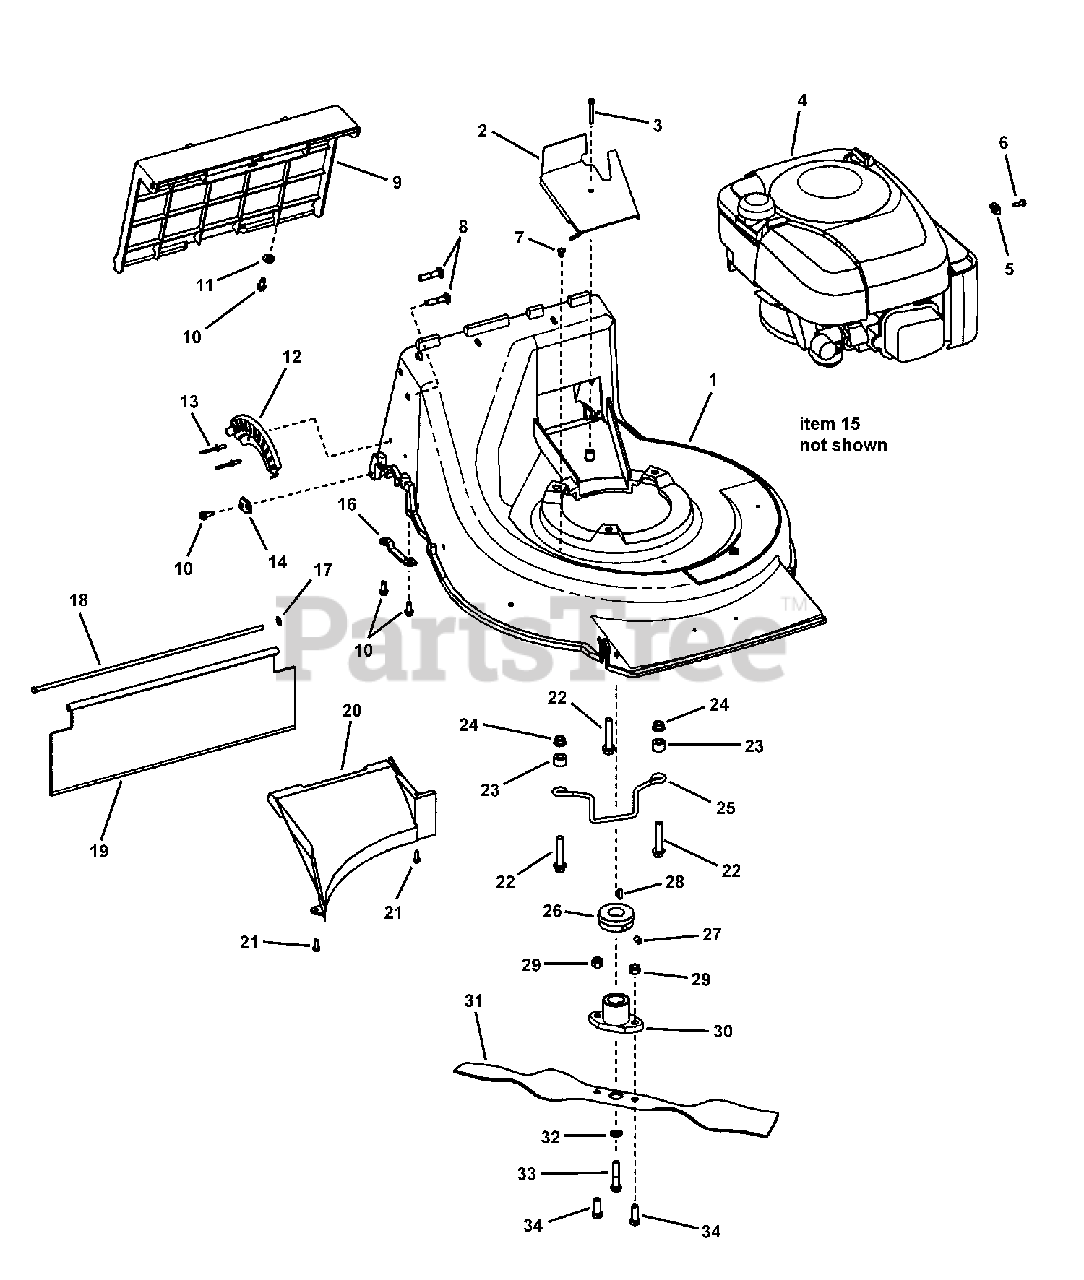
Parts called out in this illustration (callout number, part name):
1	DECK, 21" Cast Aluminum Rocker (Red)
2	BELT COVER, Commercial Metal B&S
3	SCREW, #10-24 x 1-1/2" Slotted Hex Washer Head Self-Tap
5	CLAMP, Casing
6	SCREW, #10-32 x 5/8" Self-Tap
7	PLUG, Hole (Polyethylene)
8	BOLT, 5/16-18 x 1" Round Head Carriage GR 5
9	ASSEMBLY, Discharge Door
10	SCREW, 1/4-20 x 5/8" Hex Washer Face Self-Tap
11	WASHER, .28 x .63 x .06 Flat
12	PLATE, Height Adjust
13	RIVET, 3/16 x 1/2" Steel
14	BRACKET, RH Trailing Shield Pivot Rod
16	SUPPORT, Rear Axle
17	PUSHNUT, 1/4" Black
18	ROD, Trailing Shield Pivot (1/4" Dia. x 16-1/4" long)
19	SHIELD, Trailing, Commercial Cast
20	BAFFLE, Discharge
21	SCREW, #10-24 x 5/8" Slotted Hex Washer Head Self-Tap
22	SCREW, 3/8-16 x 2" Hex Head Self-Tap
23	IDLER SPACER
24	NUT, 3/8-16 Hex Flange Lock
25	BELT GUIDE (Wireform)
26	PULLEY, Traction Drive (25mm x 2-1/8" O.D.)
27	SET SCREW, 5/16-18 x 1/2" Hex Recess
28	KEY, Hi-Pro #HP506 (Briggs engine)
29	NUT, 3/8-16 Hex Nyloc
30	HUB, Blade Drive, 25mm Internal Dia.
31	BLADE, 21" Bagging
32	WASHER, 3/8" Split Lock (Heavy)
33	SCREW, 3/8-24 x 1-3/4" Hex Head Cap GR 5
34	SCREW, 3/8-16 x 1" Hex Head Cap, GR 5
